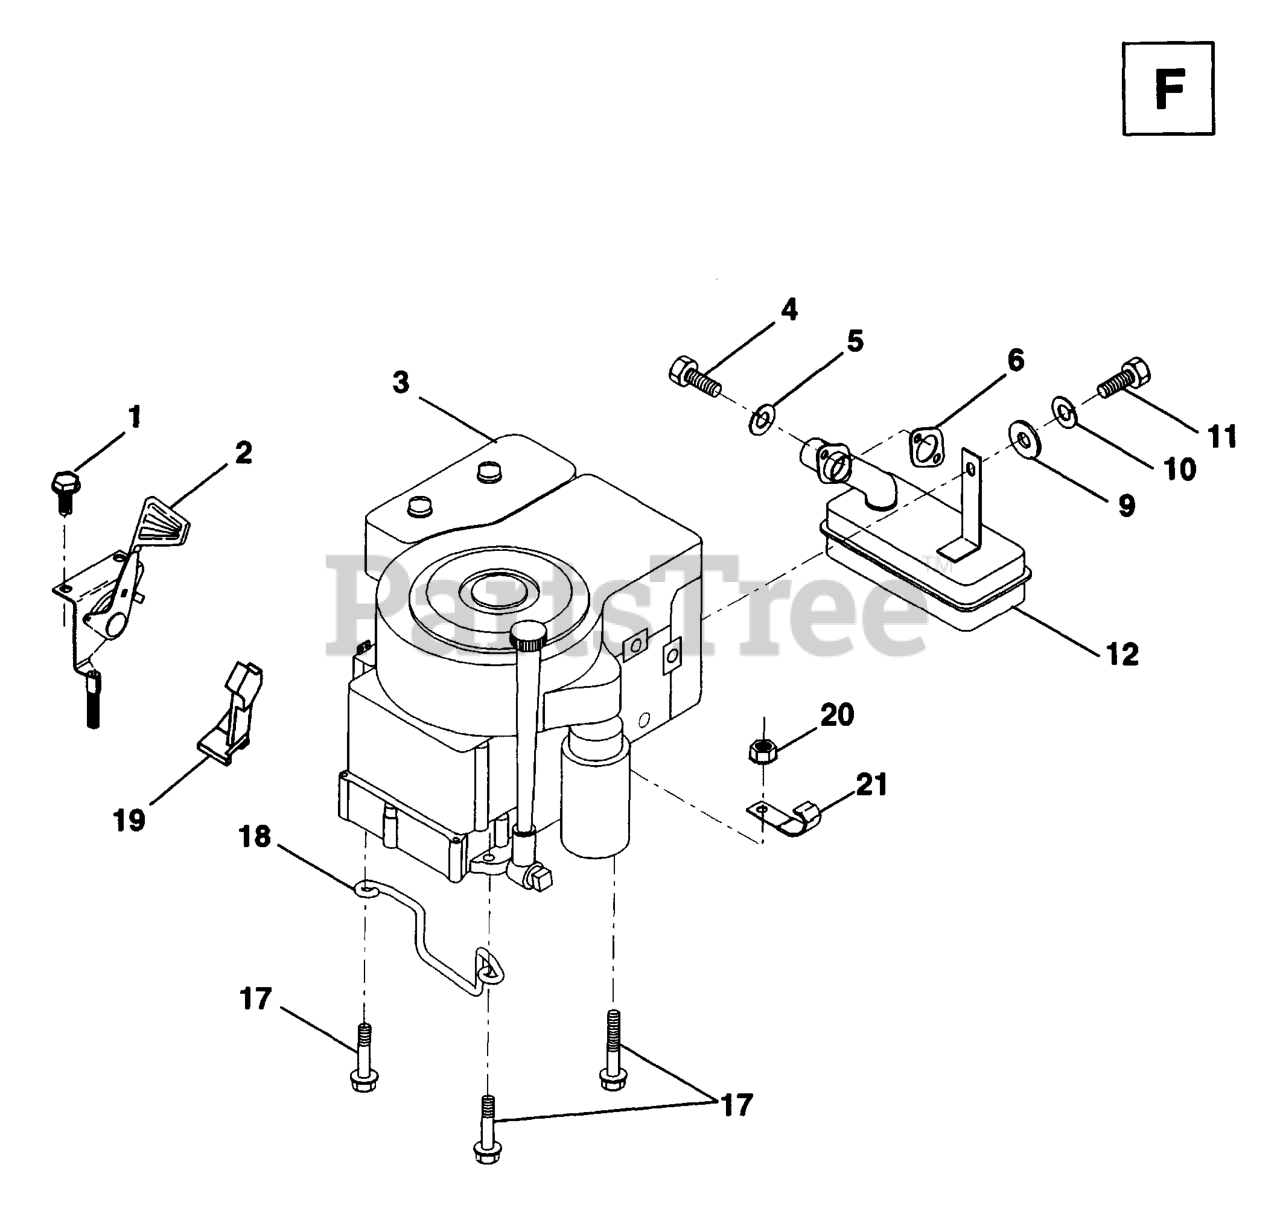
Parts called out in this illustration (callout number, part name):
1	BOLT
2	CONTROL.TH/CH.RH.BLK.FLG.EEC
4	BOLT
5	WASHER.LOCK.HVY.HLCL.SPR.5/16
6	GASKET ENGINE
9	WASHER
10	LOCKWASHER
11	BOLT.HEX.1/4.X.3/4.DICHROMATE
12	MUFFLER.SINGLE.B&S.12HP
17	SCREW LT
18	KEEPER,DR BELT GR
20	NUT.HEX.3/8-16UNC
21	CLIP T
